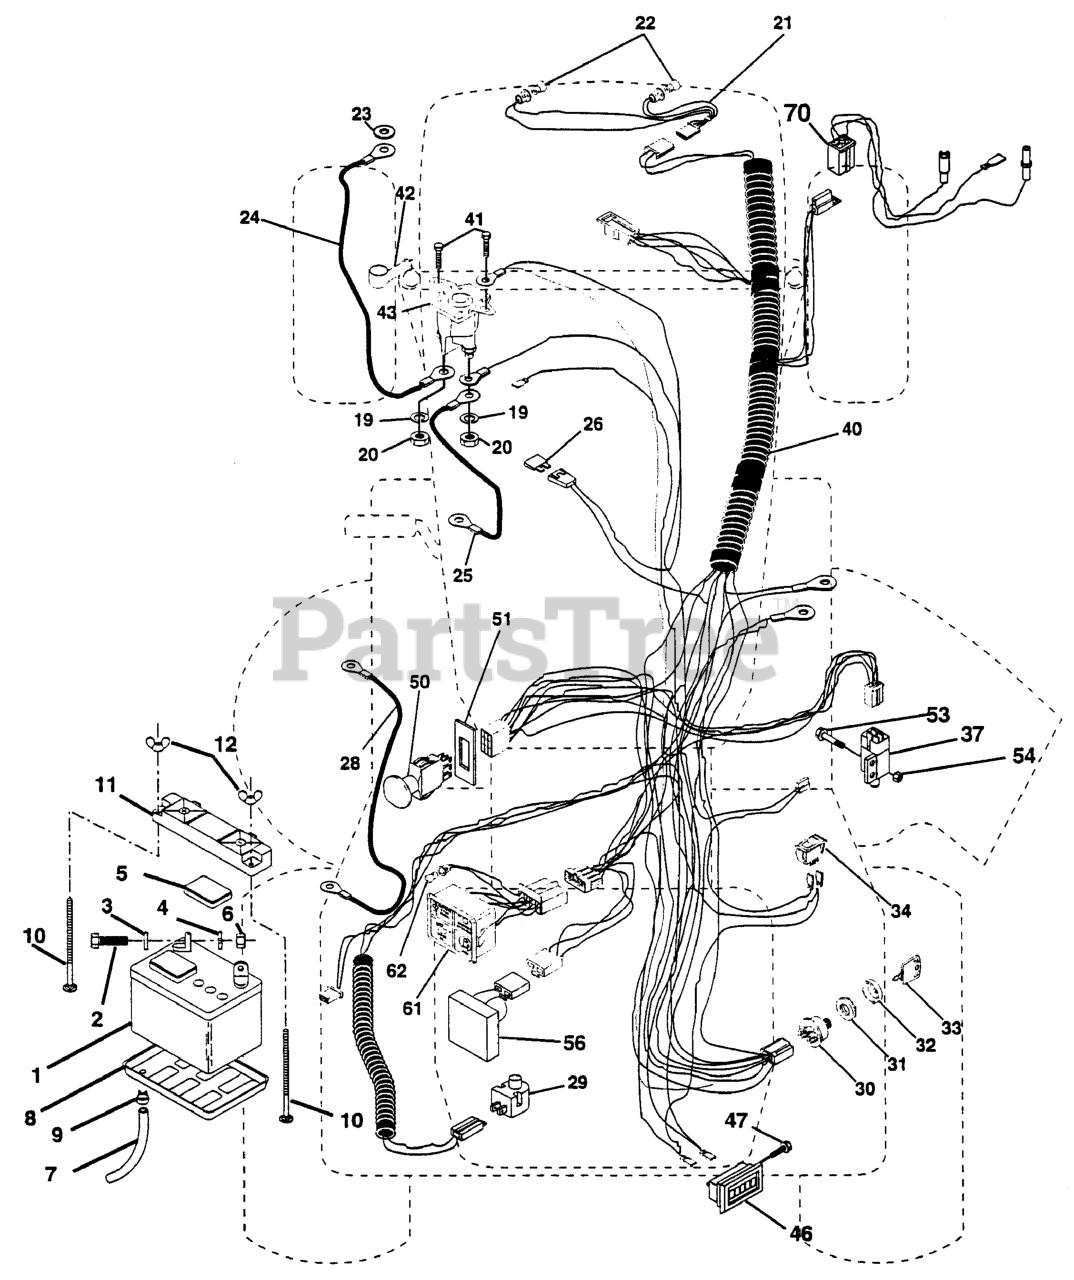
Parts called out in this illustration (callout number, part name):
1	BATTERY
2	BOLT.HEX.1/4.X.3/4.DICHROMATE
3	LOCKWASHER
4	WASHER
5	CAP BATTERY NLA
6	NUT
7	PLASTIC TUBE
8	BATTERY TRAY T
9	HOSE CLAMP T
11	TERMINAL GRD YTV
12	WING NUT
19	LOCKWASHER
20	NUT
21	HARNESS LIGHT SOC
23	Washer, Lock Int. Tooth 1/4
24	BATTERY CABLE GT
25	CABLE-BATTERY YTV
28	CABLE T
29	RP.SWITCH.PLUNGER.NC.GRAY
30	IGNITION SWITCH
31	NUT, IGNITION
32	COVER SWITCH KEY
33	KEY MLD GEN DELTA
37	SWITCH INTERLOCKT
40	IGNITION HARNESS
41	SCREW
42	TERMINAL COVER
43	SOLENOID
46	HOUR METER T
47	Screw #10-24 x 1/2
50	SWITCH-PTO
51	FRAME RETAINING RING
53	SCREW **
54	Nut Keps #10-32
56	SENSOR LOW VOLTAGE
61	LIGHT PACKAGE
62	BULB LIGHT T
70	ENGINE HARNESS
